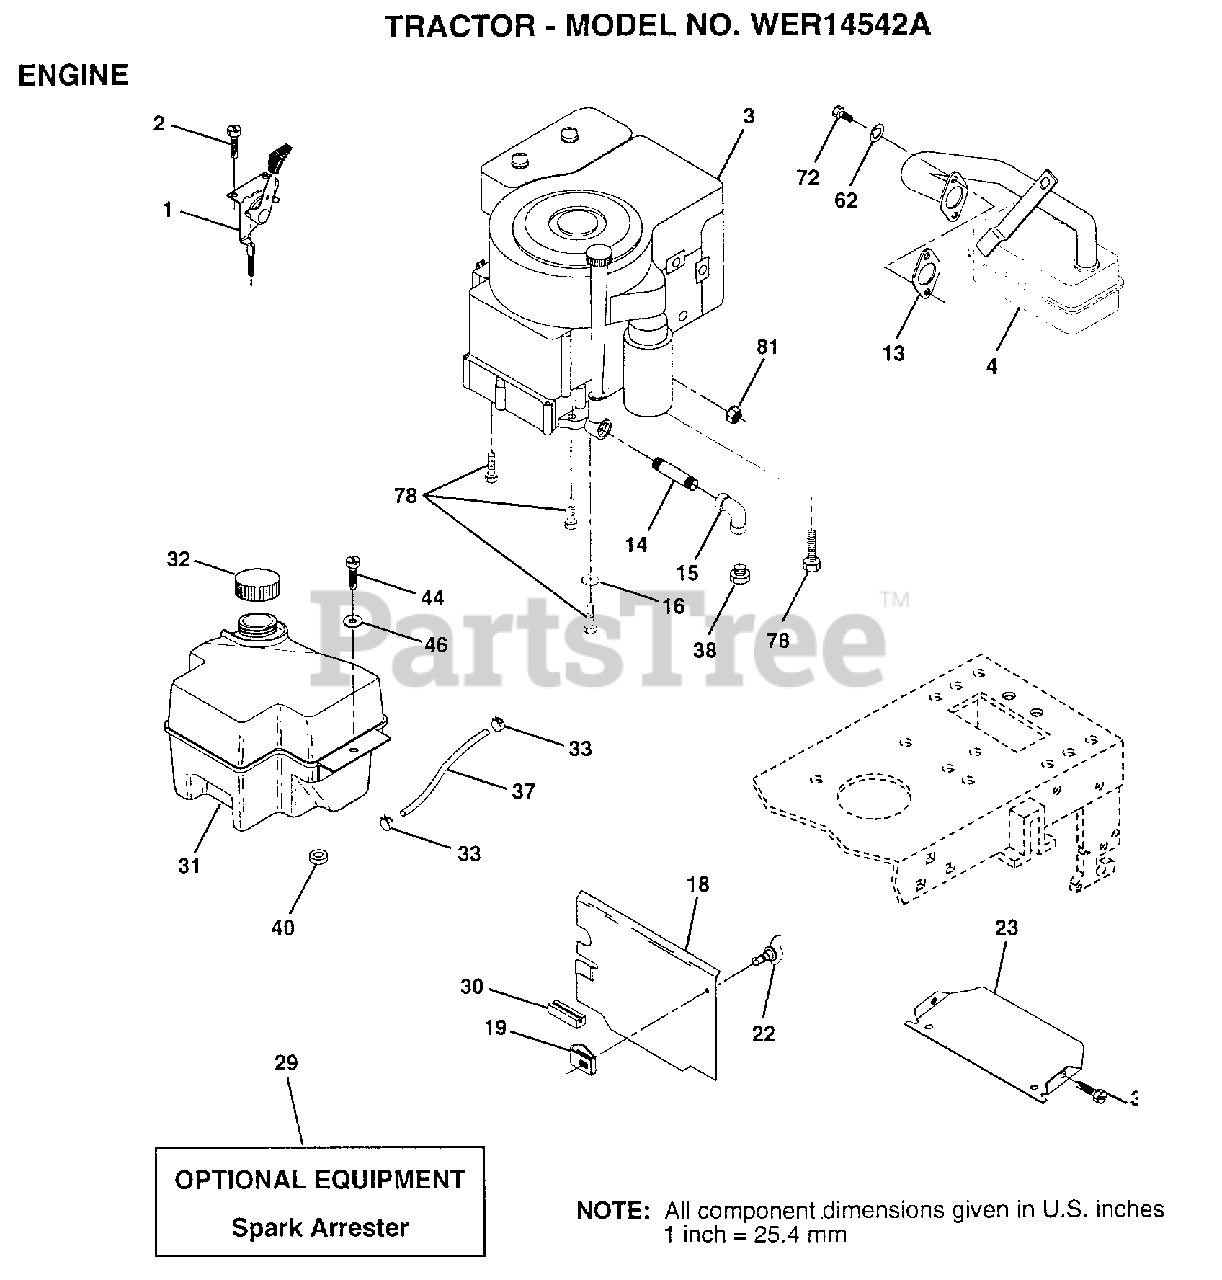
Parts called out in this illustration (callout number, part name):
1	CONTROL THROTTLE
2	SCREW LT
4	MUFFLER
13	GASKET ENG 1 313 LD TIN PLATED
14	PIPE NIPPLE
15	ELBOW
16	LOCKWASHER
18	SHIELD HEAT
19	RECEPTACLE LT
22	"STUD 1/4 TURN,BUS"
32	CAP ASM FUEL
33	HOSE CLAMP
35	SCREW
37	LINE FUEL
44	SCREW HEX CRT
46	WASHER
62	LOCKWASHER
72	SCREW
78	SCREW
81	NUT
